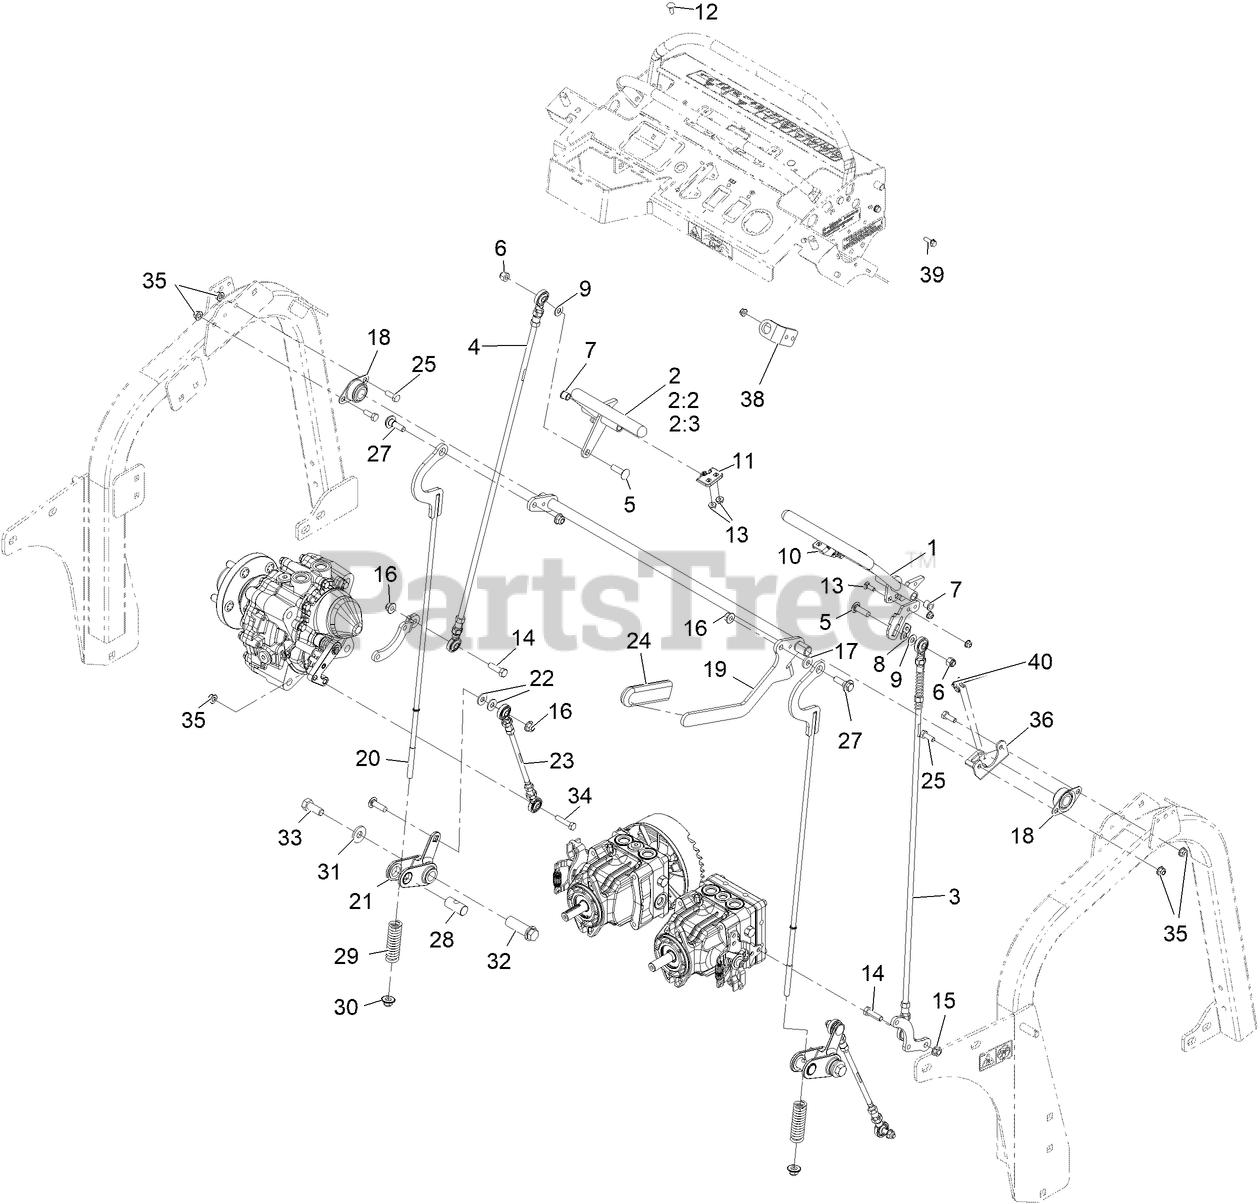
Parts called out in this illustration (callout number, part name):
1	LH CONTROL HANDLE ASM
2	RH CONTROL HANDLE ASM
2:2	Grommet-Rubber
2:3	GRIP-CONTROL, MOTION
3	LH CONTROL ROD ASM
4	RH CONTROL ROD ASM
5	Bolt-Carriage 3/8-16 X 1 1/4
6	NUT-LOCK, NI
7	BEARING
8	BRACKET-ADJUSTMENT, SPEED
10	TAB-PIVOT, LH
11	TAB-PIVOT, RH
12	BOLT-CARR
14	SCREW-HH
15	NUT-HHF, WHIZ
16	NUT-HF, NI
18	BEARING-FLANGE, SIDE
19	SHAFT-BRAKE, PARKING
21	BELLCRANK-BRAKE W/BUSHING
22	WASHER-FLAT
23	TURNBUCKLE ASM
24	GRIP-LEVER
25	SCREW-HH
27	SCREW-SHOULDER, HWH
28	PIN-TRUNION
29	SPRING-COMPRESSION
30	Nut-Nyloc 3/8-16 Flg
31	WASHER-SPRING
32	HUB-THREADED
33	SCREW-HH
34	SCREW-HH
35	NUT-HF, NI
36	BRACKET-SWITCH, BRAKE
38	BRAKET-SWITCH
39	SCREW-HHF
40	TIE-CABLE
